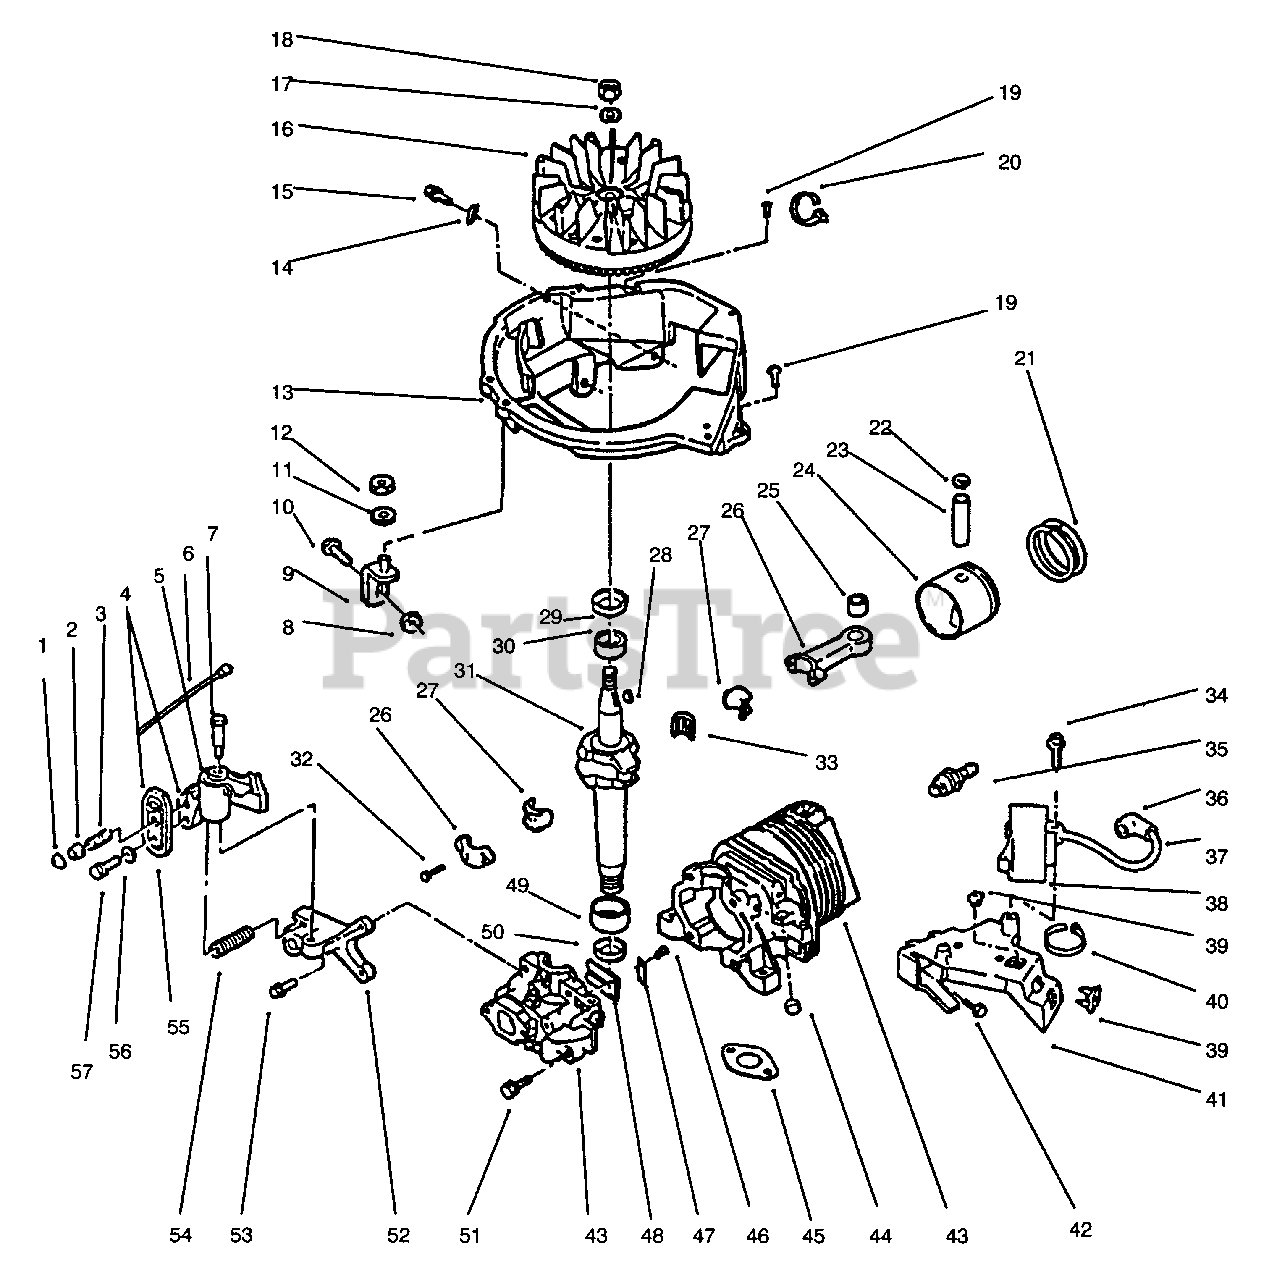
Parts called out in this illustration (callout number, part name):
1	Retainer
2	Actuator-Brake Lever
3	Spring-Cable, Return
4	Assembly-Switch (Incl. Ref. #1, 6, 20, & 56-58)
5	Assembly-Brake
6	Wire Lead
7	Bolt-Shoulder
9	Assembly-Brace
13	Shroud-Base
14	Clip-"J"
16	Assembly-Flywheel
17	Washer-Lock
18	Nut-Flywheel
20	Tie Strap
21	Set-Ring
22	Ring-Retaining
23	Pin-Wrist
24	Assy.-Piston & Conn. Rod (Incl. Ref. #24-27, & 32-33)
25	Assembly-Bearing
26	Assembly-Connecting Rod (Incl. Ref. #25-27 & 32-33)
27	Liner-Split
28	Key-Flywheel
29	Seal-Oil
30	Bearing-Main
31	Crankshaft
33	Set-Needle Bearing
34	Screw
35	Spark Plug
36	Cover-Terminal
37	Wire Lead
38	C. D. Ignition Module (Incl. Ref. #36-37)
39	Grommet
40	Tie Strap
41	Bracket-C. D.
42	Screw
43	Assy.-Cyl./Crankcase Cov. (Incl. Ref. # 46-48,51 & 53)
45	Gasket-Exhaust
47	Plate-Reed
49	Bearing-Main
50	Seal-Oil
52	Bracket-Brake
54	Spring-Brake
55	Assembly-Case
57	Screw
